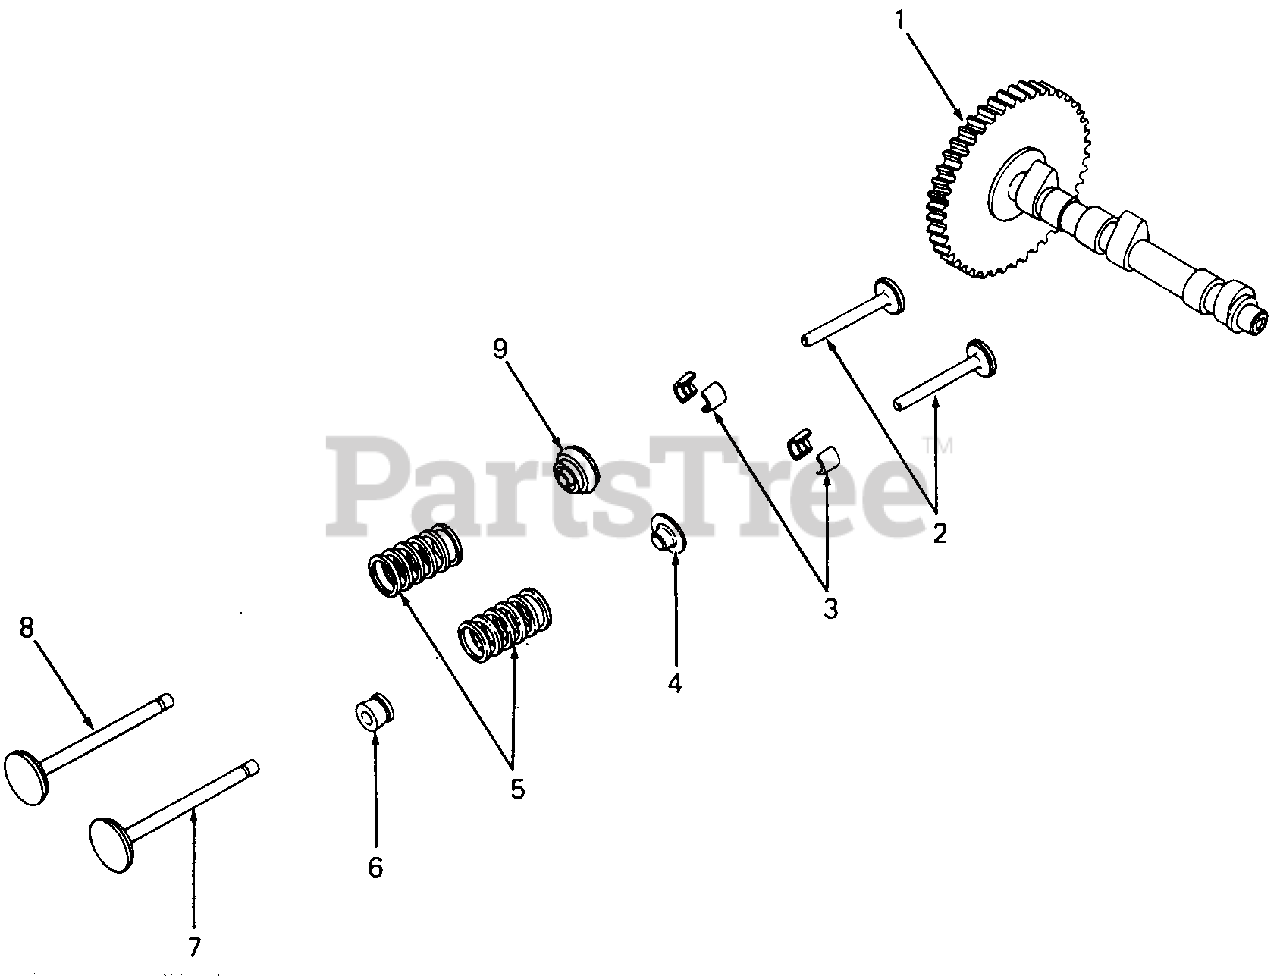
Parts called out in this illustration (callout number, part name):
1	Camshaft
3	Kit, Retainer
4	Retainer, Valve Spring
5	Spring, Valve
6	Seal, Intake Valve Stem
7	Valve, Intake
8	Valve, Exhaust
9	Rotator Valve
